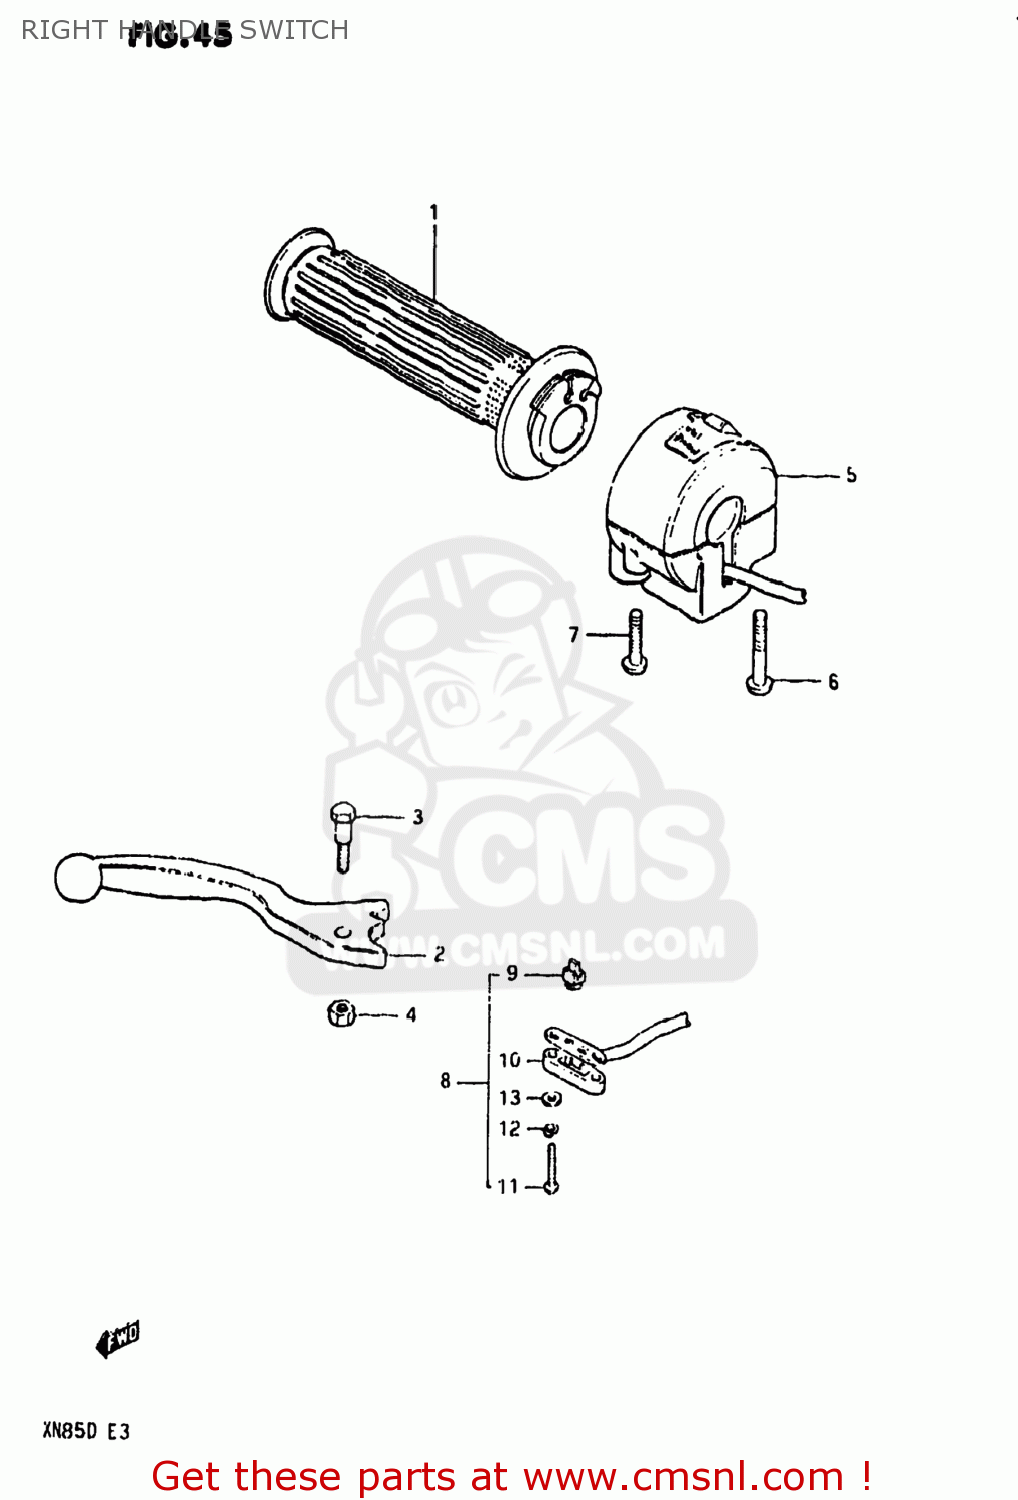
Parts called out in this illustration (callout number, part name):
1	GRIP,THROTTLE
2	LEVER,BRAKE
3	BOLT
4	NUT 6MM
5	SWITCH ASSEMBLY,HANDLE,RIGHT
6	SCREW
7	SCREW
8	SWITCH ASSEMBLY
9	CONTACT,SWITCH
10	COVER,FR BK TERMINAL BASE
11	SCREW
12	LOCK WASHER
13	WASHER
